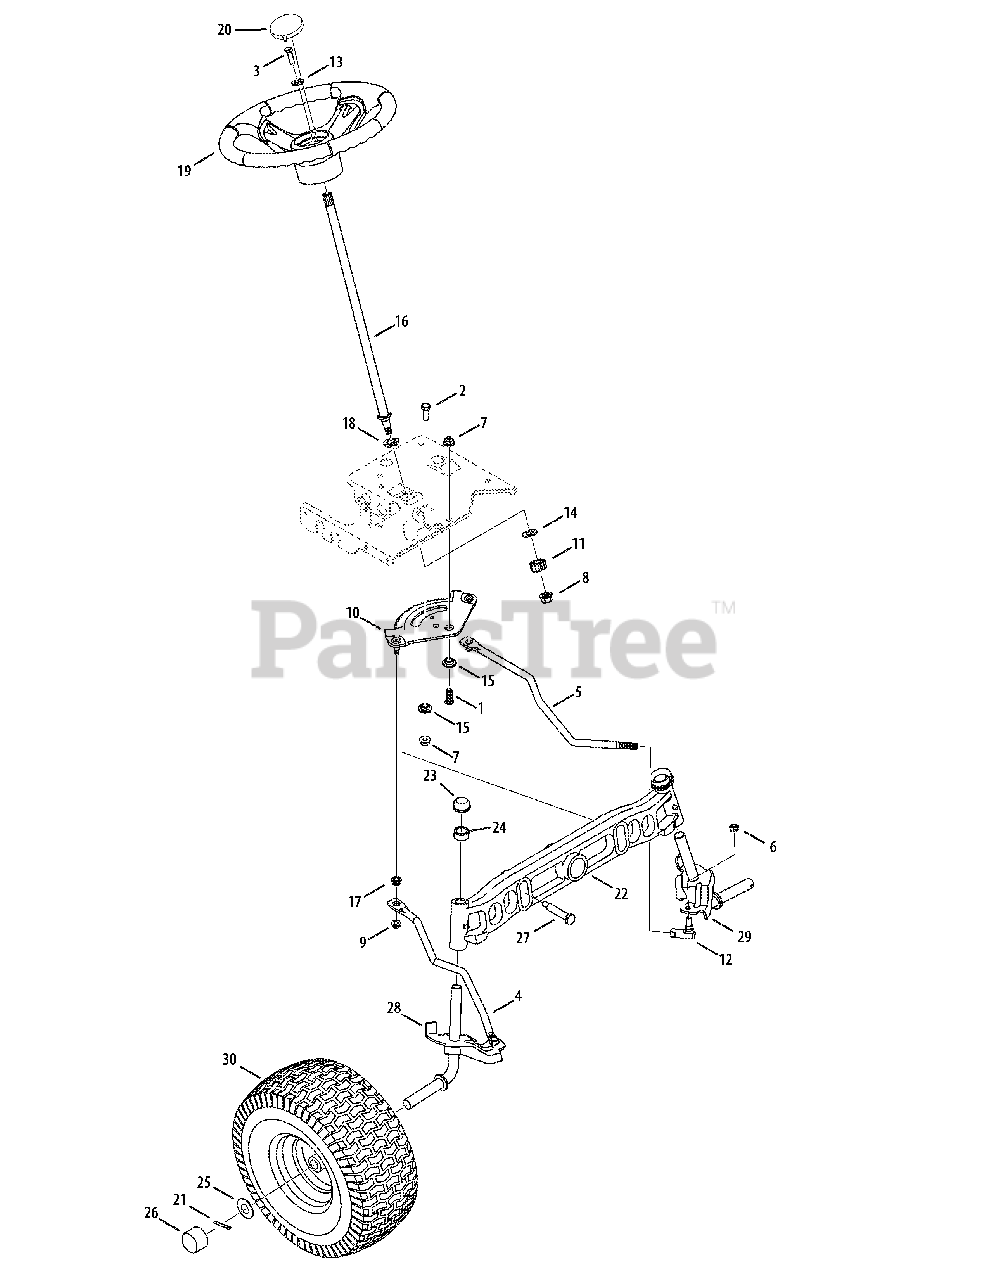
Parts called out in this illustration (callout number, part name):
1	Hex Screw, 3/8-16, 1.00, Gr5
2	Hex Screw, 3/8-16, 1.00, Gr5
3	Hex Screw, 5/16-18, 1.00, Gr5
4	Link, Drag, RH
5	Link, Drag, LH
6	Nut, Hex Lock, 3/8-24
7	Nut, Flange Lock, 3/8-16
8	Nut, Flange Lock, 7/16-20
9	Nut, Flange Lock, 5/16-18, Gr5
10	Gear, Steering, 11/90 Ratio
11	Gear, Pinion, Steering
12	Ball Joint, 7/16-20, Lock
13	Washer, Flat,.406 x .875 x .105
14	Washer, Flat,.51 x 1.12 x.06
15	Spacer, Shoulder,.38 x 1.00 x .31
16	Shaft, Steering, .625 OD x 24.25
17	Plastic Bushing.380 ID
18	Hex Flange Bearing 5/8 PM
19	Steering Wheel, 13.25
20	Steering Wheel Cover, w/ Logo
21	Cotter Pin, 5/32 x 1.25
22	Pivot Bar Axle
23	Small Cap
24	Spacer, .71 x .125 x .56
25	Flat Washer, .781 x 1.589
26	Hub Cap
27	Shoulder Bolt, .500 x 2.38, 3/8-16
28	Axle Assembly (50" Deck Units) RH
29	Axle Assembly (50" Deck Units) LH
30	Tire Only 15 x 6 x 6 Sq. Shldr.
